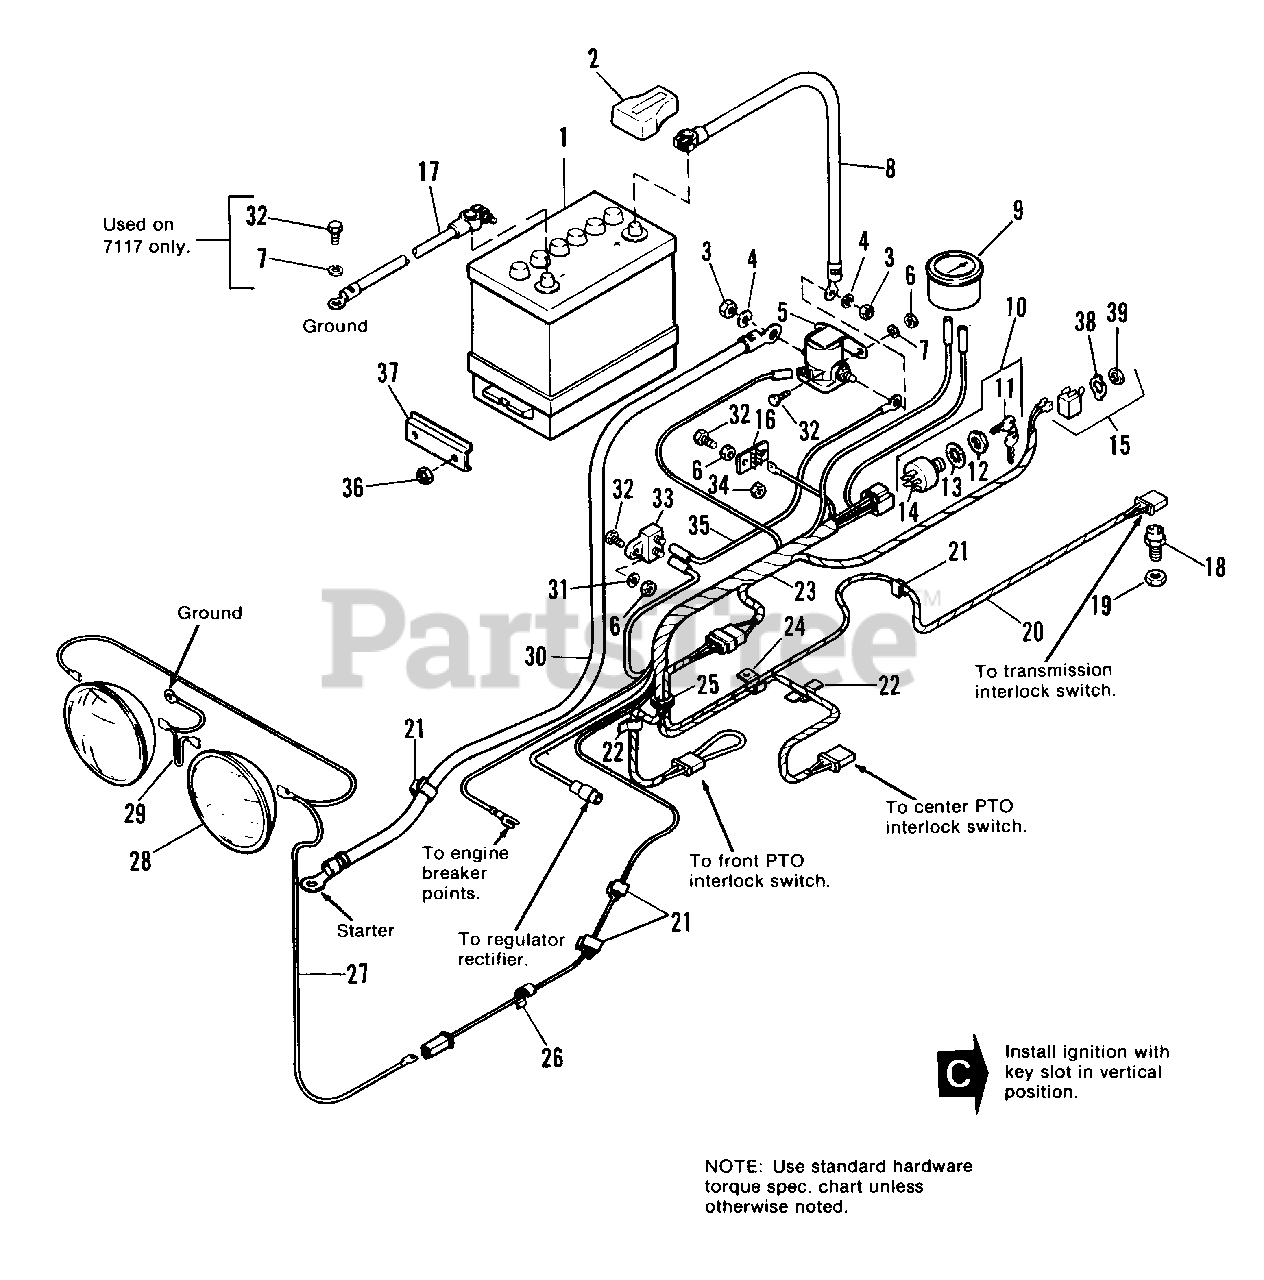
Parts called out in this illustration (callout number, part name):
1	BATTERY (Includes Decals)
2	PROTECTOR, Terminal
3	NUT, Hex, Full, 5/16-18
4	LOCKWASHER, 5/16
5	SOLENOID, Starter
6	NUT, Hex, Full, 1/4-20
7	LOCKWASHER, 1/4 (Qty. 3 on 7117)
8	CABLE (Battery to Solenoid)
10	SWITCH & KEY ASSY., Ignition
11	KEY SET (2)
12	NUT, Special
13	LOCKWASHER, Int., 5/8
15	SWITCH, Toggle
16	BOARD, Terminal
17	CABLE (Battery to Ground)
18	SWITCH, Interlock
19	NUT, Pal
20	WIRE ASSY.
21	CLIP, Tinnerman
22	CLIP, Tinnerman
23	HARNESS ASSY.
24	CLIP, Cable
26	CLIP, Tinnerman
28	LAMP, Sealed Beam, G.E. #4411-1
29	WIRE ASSY.
30	CABLE (Solenoid to Starter)
31	LOCKWASHER, 1/4
32	CAPSCREW, Hex Hd., 1/4-20 x 5/8 (Qty. 6 on 7117)
33	BREAKER, Circuit
34	LOCKNUT, Hex, 1/4-20
36	LOCKNUT, Elastic, 5/16-18
39	NUT, Switch
